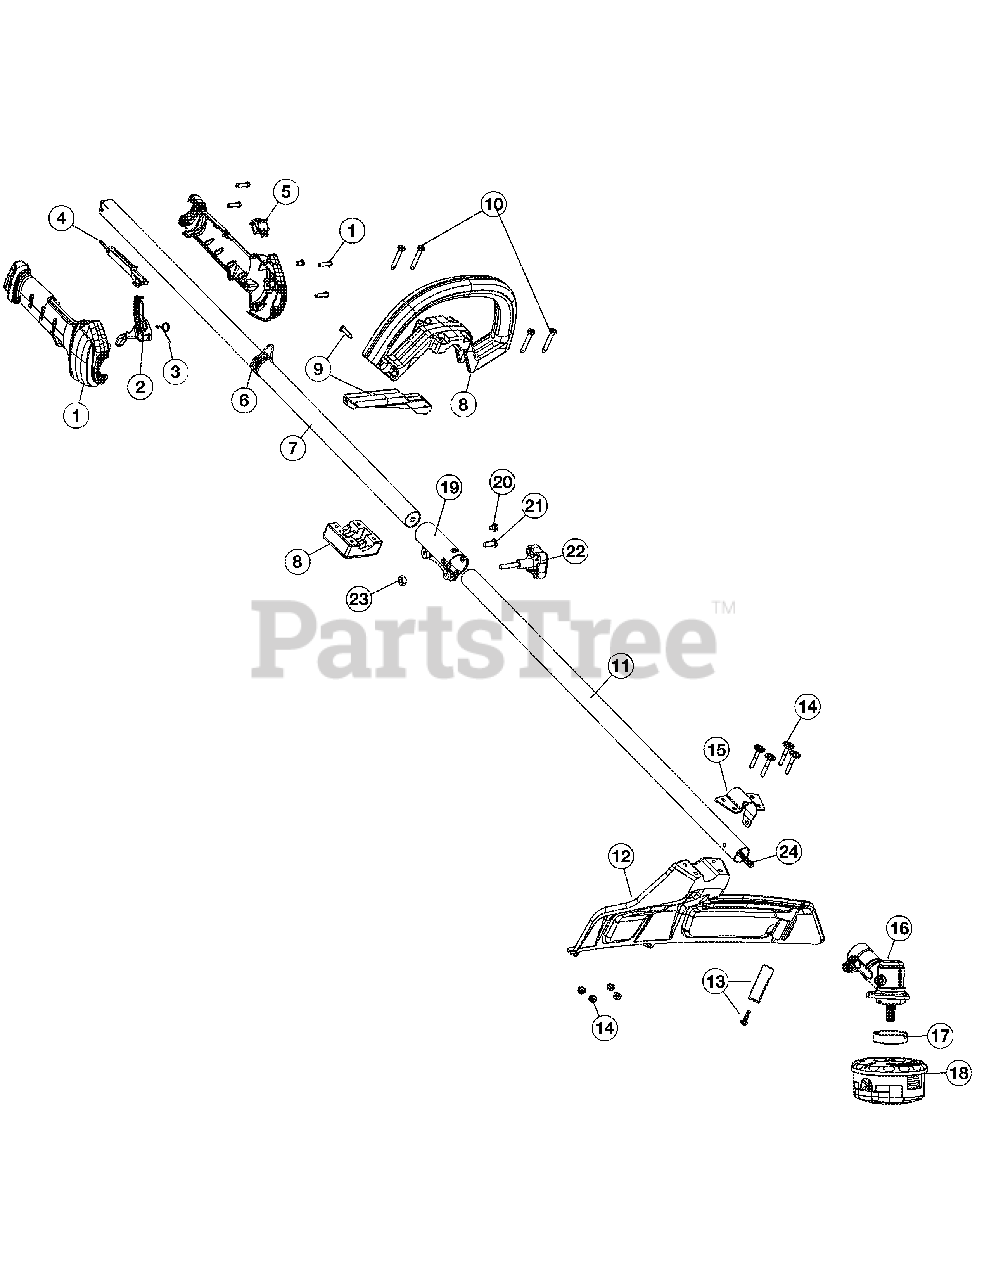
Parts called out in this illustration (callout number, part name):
1	Throttle Housing Assembly (includes 2-5)
2	Throttle Trigger
4	Throttle Lock-out
6	Shoulder Strap Clip
7	Upper Drive Shaft Housing Assembly
8	D-Handle Assembly (includes 9 & 10)
9	Barrier Bar Assembly
11	Lower Drive Shaft Housing Assembly
12	Shield Assembly (includes 13)
13	Blade Assembly
15	Guard Mounting Bracket
17	Gearbox Spacer
18	Cutting Head Assembly
19	Split Boom Coupler (includes 20-23)
22	Adjustment Knob
23	Knob Retaining Nut
24	Lower Flexible Drive Shaft
